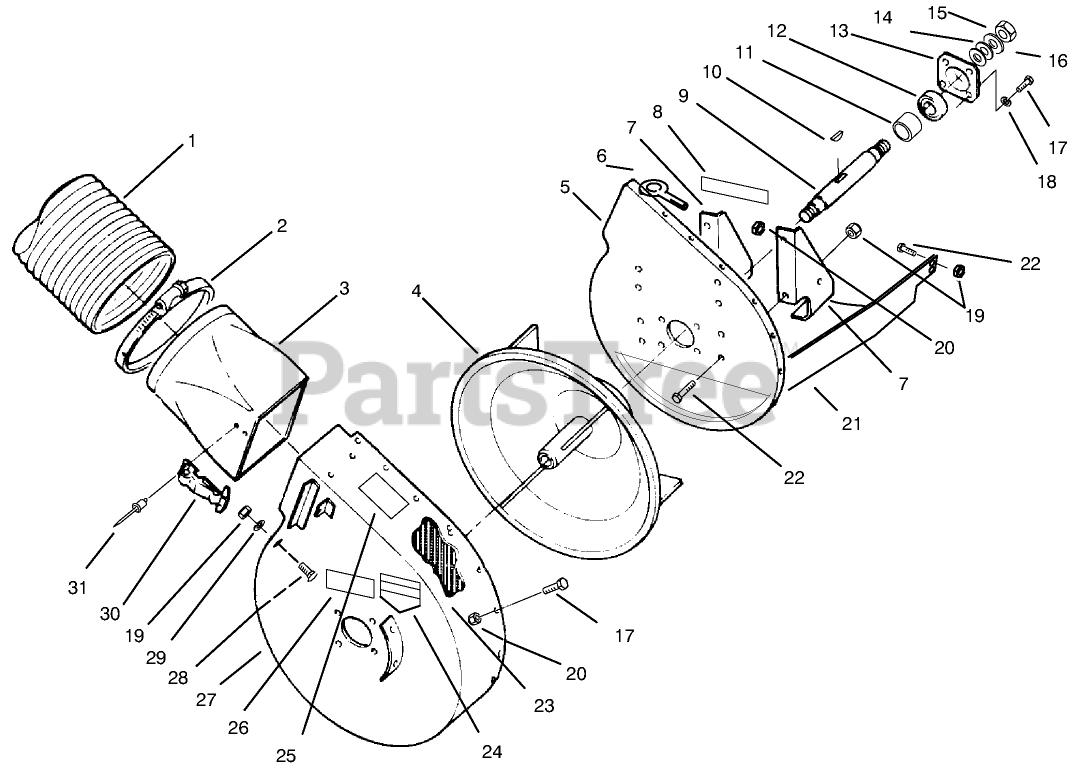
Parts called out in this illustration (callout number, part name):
1	Hose-Flexible (Ref.)
2	CLAMP
3	ADAPTER
4	IMPELLER - WELDED BLACK
5	Mount Plate Asm (Incl. Ref. #8)
6	EYE BOLT
7	BRACKET-BLOWER MT B
8	DECAL
9	SHAFT- BLOWER
11	SPACER
12	BEARING-BALL
13	CUP-BEARING
14	WASHER-FLAT
15	NUT 5/8-11 L.H.
16	WASHER-FLAT
17	SCREW-HH
18	WASHER-LOCK
19	NUT-LOCK, NI
20	NUT-LOCK, NI
21	DEFLECTOR-W.A. B
22	SCREW-HH
23	STRIP-WEAR
24	DECAL-DANGER
25	DECAL-DANGER
26	DECAL-DANGER
27	Blower Housing Asm (Incl. Ref.# 23, 25 &26)
28	BOLT-CARR
29	WASHER-PLAIN
30	HANDLE ASM
31	RIVET-POP
